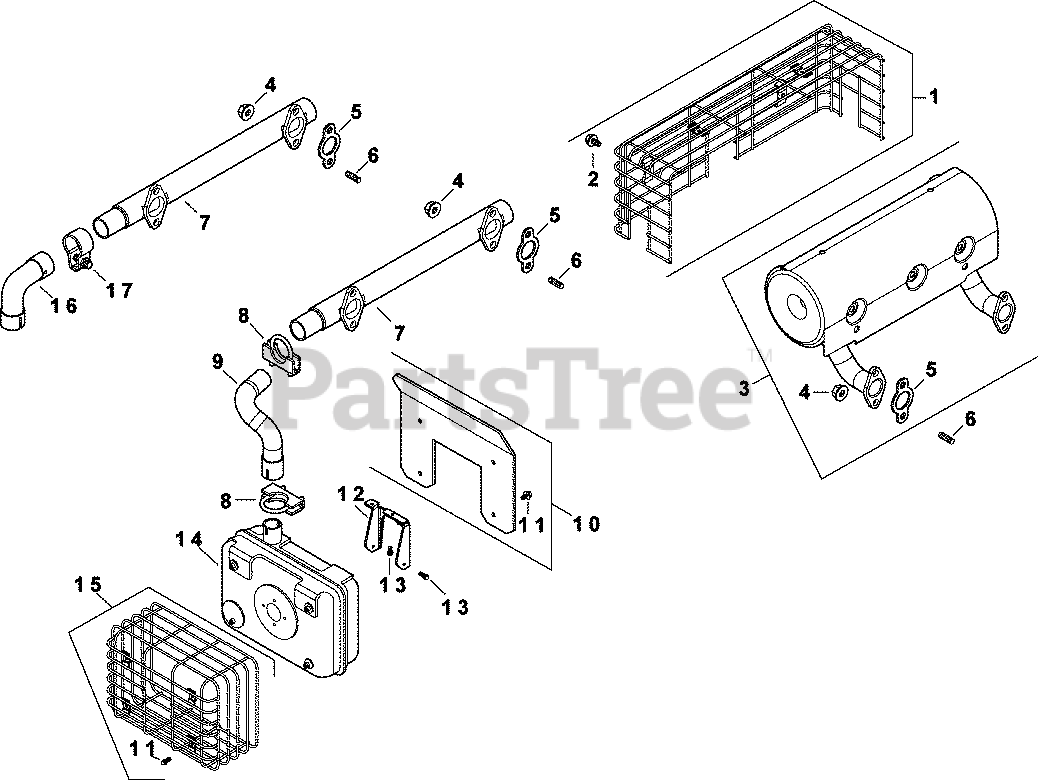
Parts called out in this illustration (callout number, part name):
4	NUT, FLG M8X1.25-(#DSC)
5	GASKET, EXHAUST
6	STUD, EXHAUST (KM)-USE 25 072 24-S
7	MANIFOLD, EXHAUST - DISCONTINUED
8	CLAMP, MUFFLER
10	KIT, HEAT SHIELD
11	SCREW, HVY FLG M5X.8X10
13	SCREW,FLG THD FRM M6X1.0X16-(#25086397S)
15	KIT, MUFFLER GUARD
